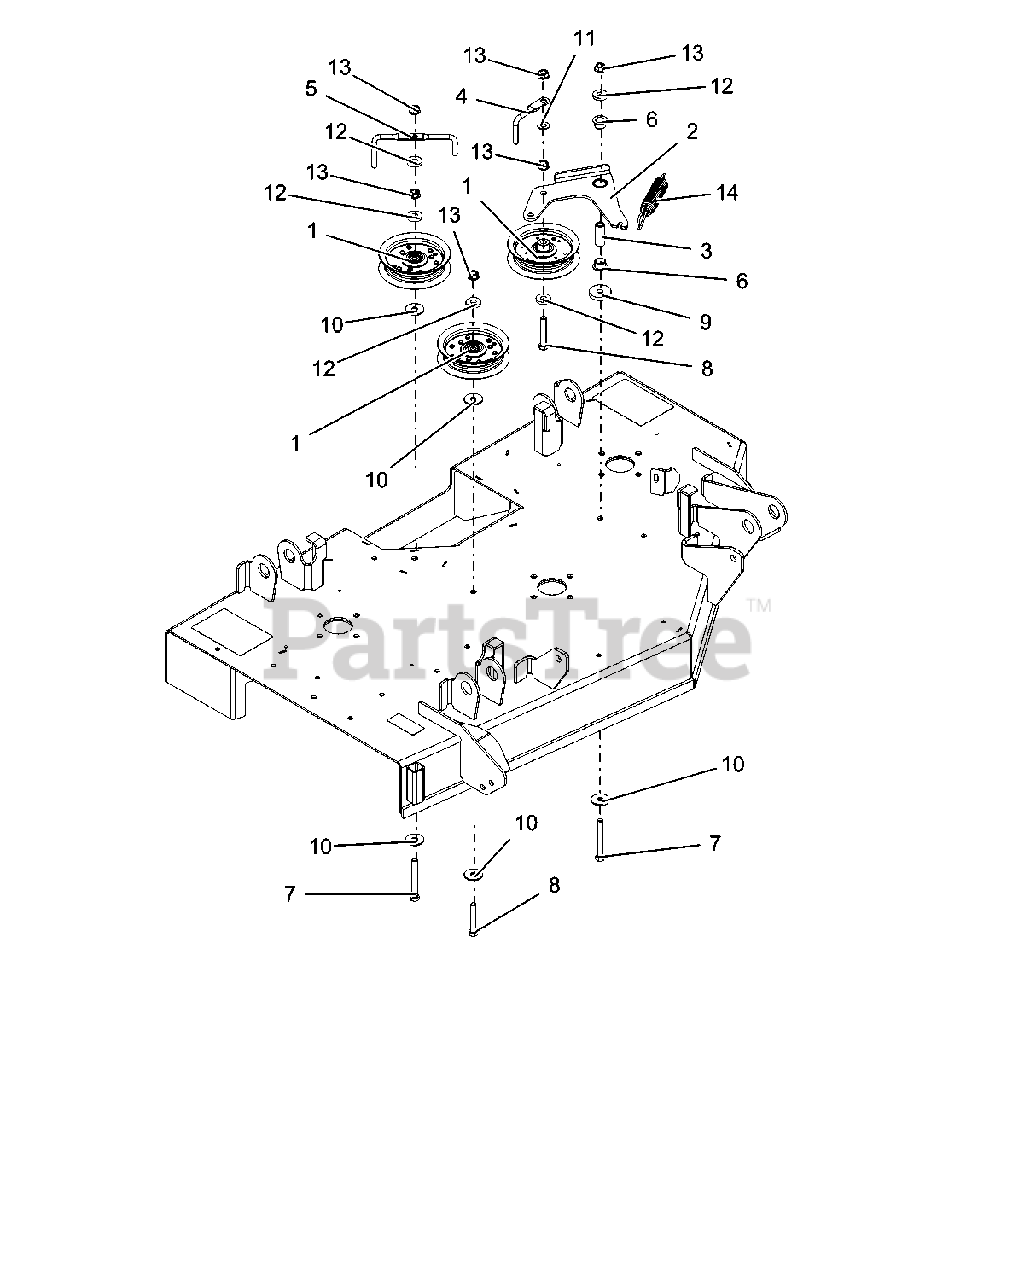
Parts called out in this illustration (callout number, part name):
1	ASM, IDLER 4"
2	WLDMT, IDLER ARM-42"
3	SPACER, .375IDX.625ODX1.66 PM
4	WIREFORM, BELT FINGER
5	WIREFORM, BELT FINGER
6	BSHG-FLG, .625X.750X.500X1.00
7	BLT-HEX .38-16X3.00 GR5 FTH YZ
8	@BLT-HEX .38-16X2.25 GR5 YWZC
9	WSHR,FLT STL.406X1.50X.245YWZC
10	@WSHR-FL-STL .406X1.25X.10 ZC
11	@WSHR-FL-STL.406X.812X.065 YWZ
12	WSHR-FL-STL .406X1.00X.188 YWZ
13	@NUT-LK-TOP-FLG .38-16 YWZC
14	SG-TENS .135X.98X6.0 WLD 62
